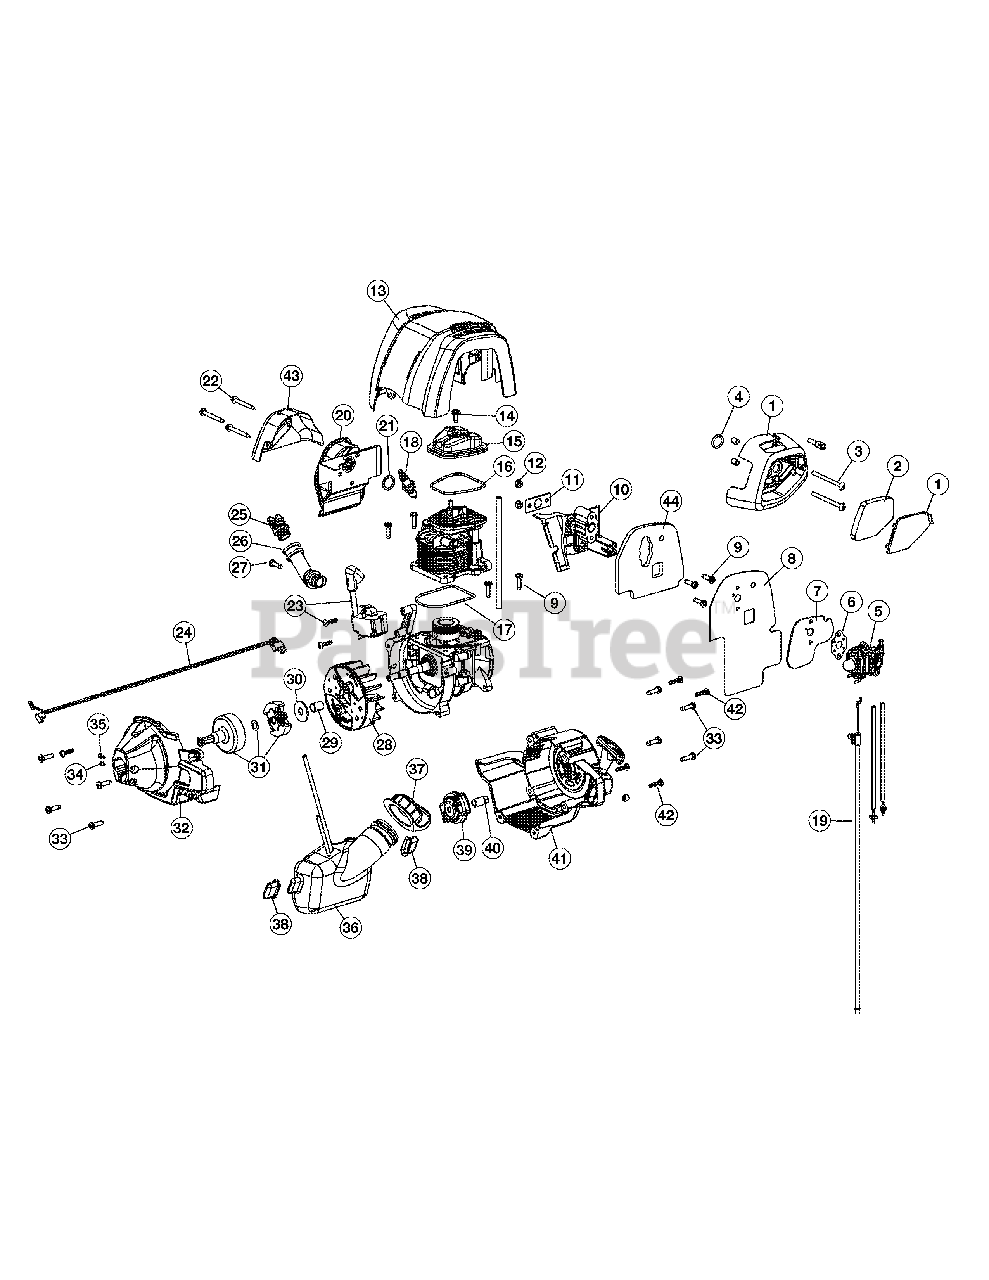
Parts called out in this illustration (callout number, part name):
1	Air Cleaner Assembly
2	Air Filter
4	Carburetor O-Ring
5	Carburetor Assembly
6	Carburetor Gasket
8	Carburetor Baffle
9	Screw
11	Insulator Gasket
13	Engine Cover
15	Valve Cover
16	Valve O-Ring
17	Cylinder O-Ring
18	Spark Plug
19	Throttle Cable
20	Muffler Assembly
21	Muffler Gasket
22	Muffler Bolt
23	Module Assembly
24	Lead Wires
25	Oil Plug Assembly
26	Oil Fill Tube Assembly
30	Clutch Washer
31	Clutch Assembly
32	Clutch Cover Assembly
34	Anti-rotation Screw
35	Clamp Screw & Nut
36	Fuel Tank
38	Fuel Tank Pad
39	Pawl Assembly
40	Electric Start Adapter
41	Starter Cover Assembly
43	Muffler Shield
44	Carburetor Heat Shield
